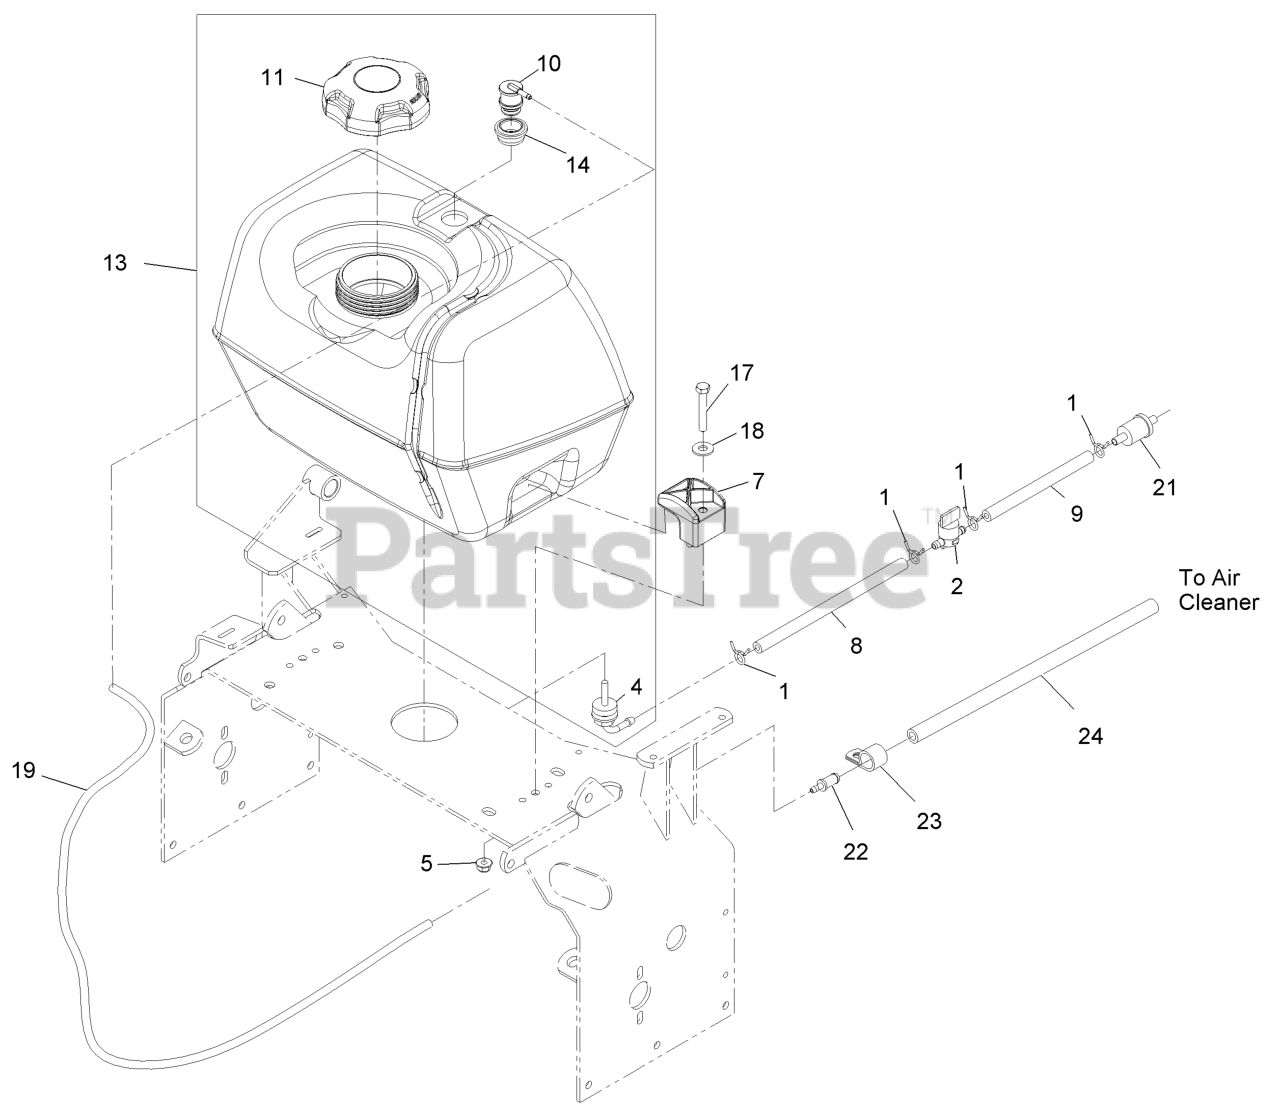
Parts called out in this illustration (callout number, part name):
2	VALVE-FUEL
4	FITTING-FUEL, BULKHEAD
5	NUT-HF, NI
8	HOSE-FUEL
9	HOSE-FUEL
17	SCREW-HH
18	WASHER-FLAT
19	HOSE-EMISSIONS
21	Pn 240513-S Filter-Fuel
22	FITTING-STRAIGHT
23	CLIP-LOOM
24	HOSE-FUEL
